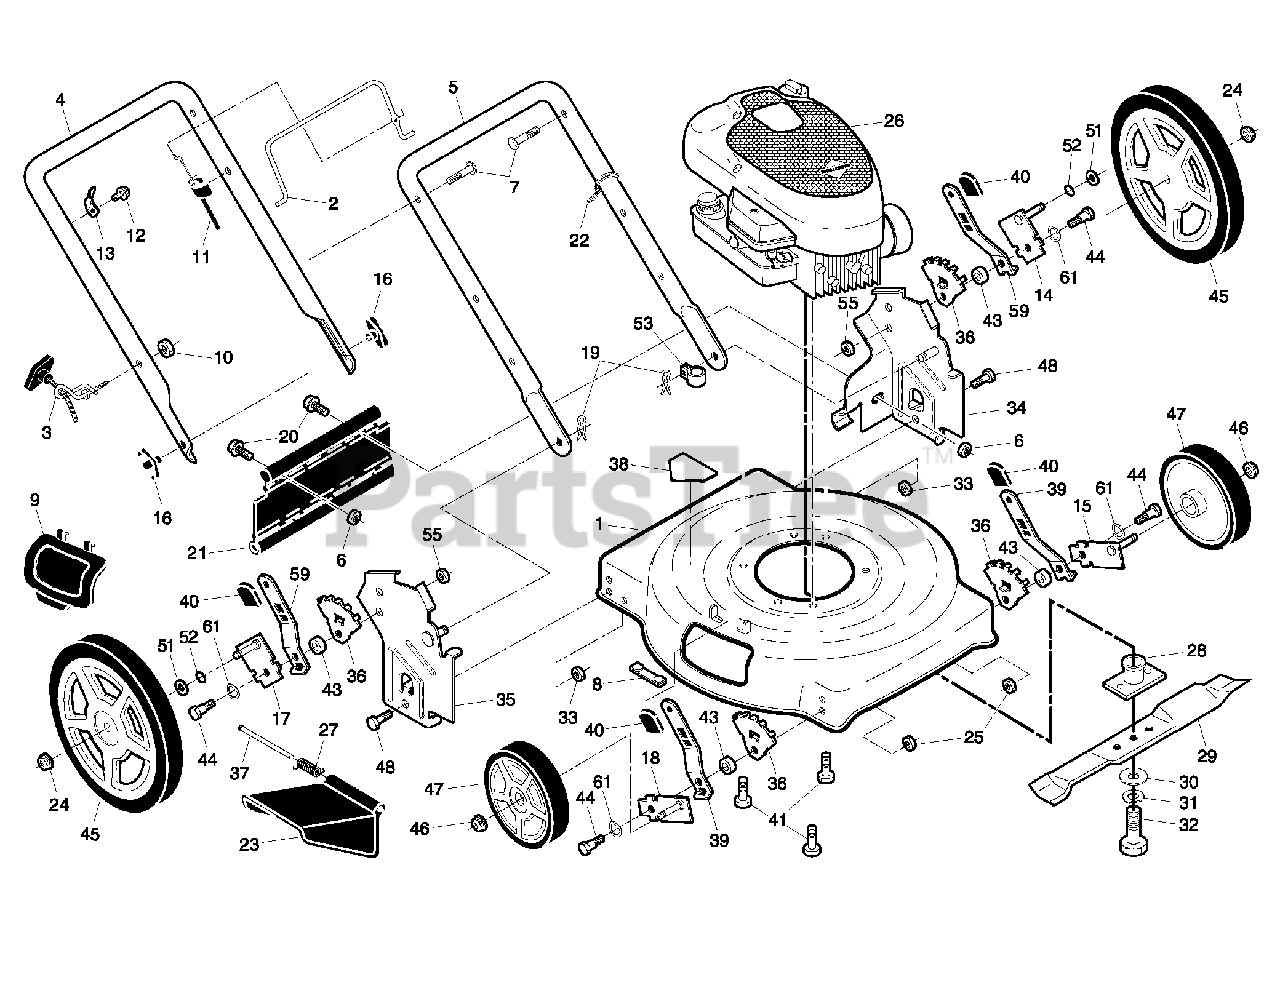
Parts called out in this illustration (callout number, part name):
1	HOUSING.22SD.ECON.PUSH.YELLOW
2	BAIL.CONT.D.STRAIGHT.PUSH.YELL
3	GUIDE.ROPE.STD.BLK.ZIN
4	HANDLE.UPPER.ECONOMY.BLACK
5	HANDLE.LOWER.D-STRAIT.BLACK
6	LOCKNUT.NYLOC.1/4-20
7	BOLT, HANDLE 5/16-18X1.75
8	CLIP. CLOSEOUT
9	PLATE.MULCHER.22.ECON.BLACK
10	NUT
11	CABLE.MZR.RATO.22"LOW.
13	BRACKET.UPSTOP.RT
14	Axle Arm Assembly, .Lr.5/9.Pos.Bzp
15	AXLE ARM ASSY FRONT LH
16	KNOB.WING.PLASTIC.BLACK
17	Axle Arm Assembly, RR 5/9 Pos BZP
18	AXLE ARM ASSY FRONT RH
19	HAIRPIN COTTER
20	BOLT.HEX.1/4.X.3/4.DICHROMATE
21	SKIRT.REAR.22RD/SD.FO/VE
22	TIE GUIDE
23	GUARD.DISCHARGE.22".
24	NUT.HEX.FLANGE.3/8-16.LOCKNUT
25	NUT.FLANGE.HEX.5/16X18.BLACK
27	SPRING.HINGE
28	BLADE ADAPTOR
29	BLADE.22.MULCH.STANDARD
30	WASHER,HARDEN
32	SCREW, HEX HD 3/8-24 X 1-3/8
33	NUT.71038.31-18.HEX.NYLOCK
34	BRKT.ASM.HDL.22.ECON.BLACK
35	BRKT.ASM.HNDL.22.ECON.HW.RH.BL
36	WHEEL ADJ BRACKET FRONT
37	HINGE ROD
38	No Step Decal
39	SELECTOR SPRING, FRONT
40	Knob
41	BOLT 3/8-16X1-1/8
43	SPACER.HEIGHT.ADJUSTER
44	SHOULDER BOLT 5/16-18
45	RP.WHEEL.12X1.75.5SPK.BRK.BLK.
46	NUT.HEX.FLANGE.3/8-16.LOCKNUT
47	WHEEL.7X1.75.5SPK.BRK.BLACK
51	WASHER PM
52	O-RING..070X.487.NEOPRENE
53	CLIP.CABLE.BLK
55	NUT.LOCK.5/16-18
59	SPRING.SEL.22.ECON.HI-WHL.RATO
61	WASHER.CURVED.CYLINDRICAL
